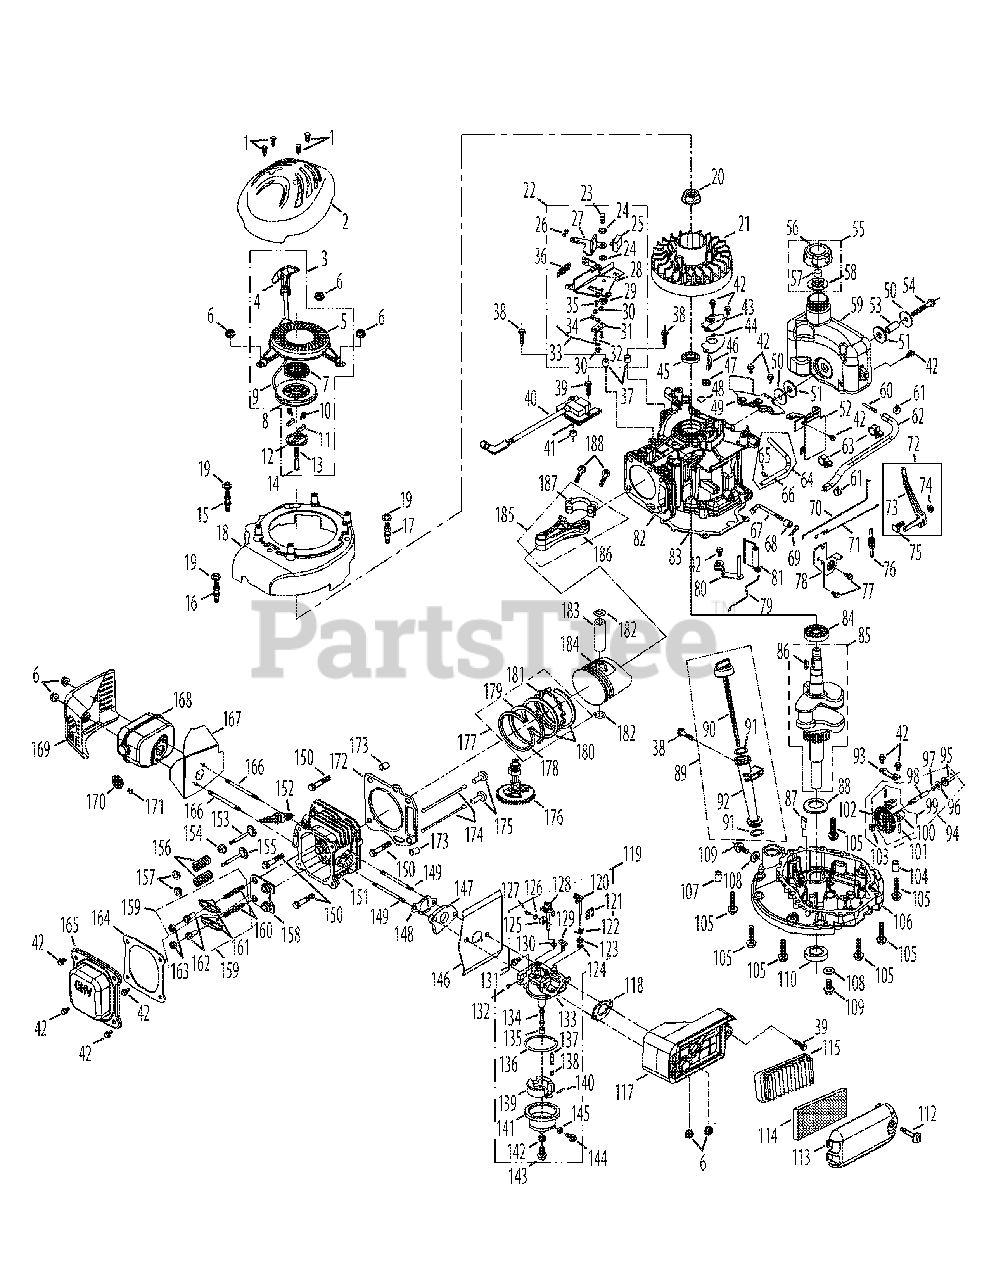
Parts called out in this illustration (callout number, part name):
1	Self-Tap Bolt, Hilo #12-16 x 1.00"
2	Engine Shroud
3	Recoil Starter Assembly
4	Starter Handle
5	Starter Housing
6	Nut M6 X 10 Mm
7	Recoil Spring and Pulley Assembly
8	Starter Pulley
9	Starter Rope
10	Starter Pawl Return Spring
11	Starter Pawl
12	Pressure Plate
13	Pressure Plate Spring
14	Pressure Plate Bolt
15	Starter/Shroud Stud Black/M6 x 75
16	Starter/Shroud Stud Front/M6 x 75.3
17	Starter/Shroud Stud White/M6 x 73
18	Inner Shroud
19	Engine Shroud Spacer
20	Flywheel Nut M14
22	Brake Assembly
37	Brake Spacer
38	Bolt M6×35
39	Bolt M6×30
40	Ignition Coil Assembly
41	Ignition Coil Spacer
42	Bolt M6×14
43	Breather Cover Plate
44	Breather Gasket
45	Upper Crankshaft Seal
46	Mesh Screen
47	Breather Valve Spring
48	Breather Valve
49	Fuel Tank Bottom Bracket
50	Fuel Tank Washer
51	Rubber Bushing
52	Tank/Label Bracket
53	Fuel Tank Bushing
54	Tank Bolt M8×50
55	Fuel Cap Assembly
56	Fuel Cap
57	Foam Insert
58	Vent Gasket
59	Fuel Tank Assembly
60	Fuel Filter
61	Fuel Hose Clamp
62	Fuel Hose
63	Plastic Support Clamp
64	Breather Hose Assembly
65	Breather Hose Clamp
66	Breather Hose
67	Governor Arm Shaft
68	Governor Seal
69	Governor Cotter Pin
70	Throttle Linkage Rod
71	Throttle Linkage Spring
72	Gover Arm Assembly
73	Governor Arm
74	Governor Arm Nut M6
75	Governor Arm Bolt
76	Governor Spring
77	Bolt M6×12
78	Throttle / Governor Bracket
79	Choke Linkage Rod
80	Air Vane Bracket
81	Air Vane
82	Crankcase
83	Crankcase Cover Gasket
84	Main Bearing
85	Crankshaft Assembly
86	Woodruff Key
87	Oil Return Seal
88	Crankshaft Thrust Washer
89	Dipstick Assembly Complete
90	Dipstick
91	Dipstick and Oil Fill Tube O-Ring
92	Tube
93	Governor Gear Mounting Plate
94	Governor Gear/Shaft Assembly
95	Governor Slide Cap
96	Governor Slide Cap Washer
97	Governor Ring
98	Governor Gear Shaft
99	Governor Gear Assembly
100	Governor Fly Weight
101	Governor Fly Weight Pin
102	Governor Gear
103	Governor Gear Washer
104	Crankcase Cover Dowel 7×14
104	Dowel Pin 7×14
105	Coil/Sump Bolt M6x28
106	Crankcase Cover
107	Dowel Pin 9×14
108	Oil Drain Plug Washer
109	Oil Drain Plug
110	Lower Crankshaft Seal
112	Air Filter Cover Thumb Screw
113	Outer Air Cleaner Cover
114	Foam Filter Element
115	Paper Filter Element
116	Breather Channel Cover
117	Inner Air Cleaner Housing
118	Carburetor Gasket Plate
119	Carburetor Assembly
120	Choke Shaft
121	Choke Plate
122	Choke Return Spring
123	Choke Shaft Washer
124	Fiber O-Ring
125	Throttle Plate
126	Throttle Plate Lock Washer
127	Throttle Plate Screw
128	Throttle Shaft
129	Idle Jet Assembly
130	Fiber O-Ring
131	Idle Speed Adjusting Screw
132	Idle Mixture Screw
133	Carburetor Body
134	Main Nozzle / Emulsion Tube
135	Main Jet
136	Fuel Bowl O-Ring
137	Needle Valve
138	Needle Valve Spring
139	Float
140	Float Pin
141	Fuel Bowl
142	Fuel Bowl Gasket
143	Fuel Bowl Mounting Bolt
144	Fuel Drain Plug
145	Fuel Drain Plug Gasket
146	Carburetor Gasket
147	Carburetor Insulator
148	Carburetor Insulator Gasket
149	Carb Stud M6x92
150	Head Bolt M8×54
151	Cylinder Head
152	Spark Plug/F6rtc
153	Intake Valve
154	Intake Valve Seal
154	Valve Seal
155	Exhaust Valve
156	Valve Spring
157	Valve Spring Retainer
158	Push Rod Guide
159	Rocker Arm Assembly
160	Rocker Arm Stud
161	Rocker Arm
162	Valve Adjustment Nut
163	Pivot Locking Nut
164	Valve Cover Gasket
165	Valve Cover
166	Muffler Stud M6x95
166	Muffler Stud
167	Muffler Gasket
167	Muffler Heat Shield Gasket
168	Muffler Assembly
169	Muffler Shield
170	Spark Arrestor
171	Spark Arrestor Screw
172	Cylinder Head Gasket
173	Cylinder Head Dowel 10×16
174	Push Rod Kit
175	Tappet
176	Camshaft Assembly
177	Piston Ring Set
178	Upper Piston Compression Ring
179	Lower Piston Compression Ring
180	Piston Oil Ring Segment
181	Piston Oil Ring Expander
182	Piston Pin Snap Ring
183	Piston Pin
184	Piston
185	Connecting Rod Assembly
186	Connecting Rod
187	Connecting Rod Cap
188	Connecting Rod Bolt
